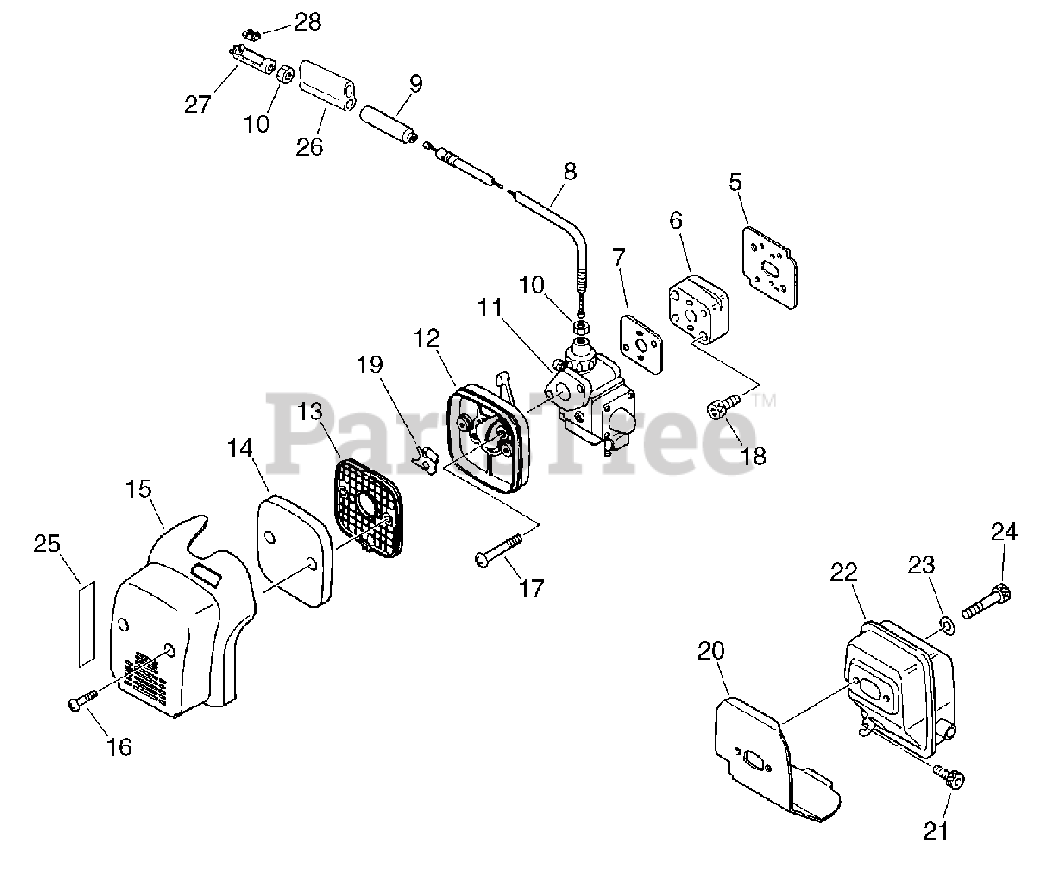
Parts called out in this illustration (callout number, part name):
5	GASKET, INTAKE
6	INSULATOR, INTAKE
7	GASKET, INTAKE
8	CABLE, THROTTLE
9	TUBE - VINYL
11	CARBURETOR
12	CASE, AIR FILTER
13	RETAINER, AIR FILTER
14	FILTER, AIR
15	COVER, AIR FILTER
16	SCREW - 4X20
17	SCREW - 5X50
18	SCREW - 5X25
19	SPRING, CHOKE
20	GASKET, EXHAUST
21	SCREW - 5X12
22	MUFFLER
22	MUFFLER ASSY
23	WASHER - 5
24	SCREW - 5X60
25	LABEL - CHOKE
27	CONNECTOR, CABLE
28	CONNECTOR
